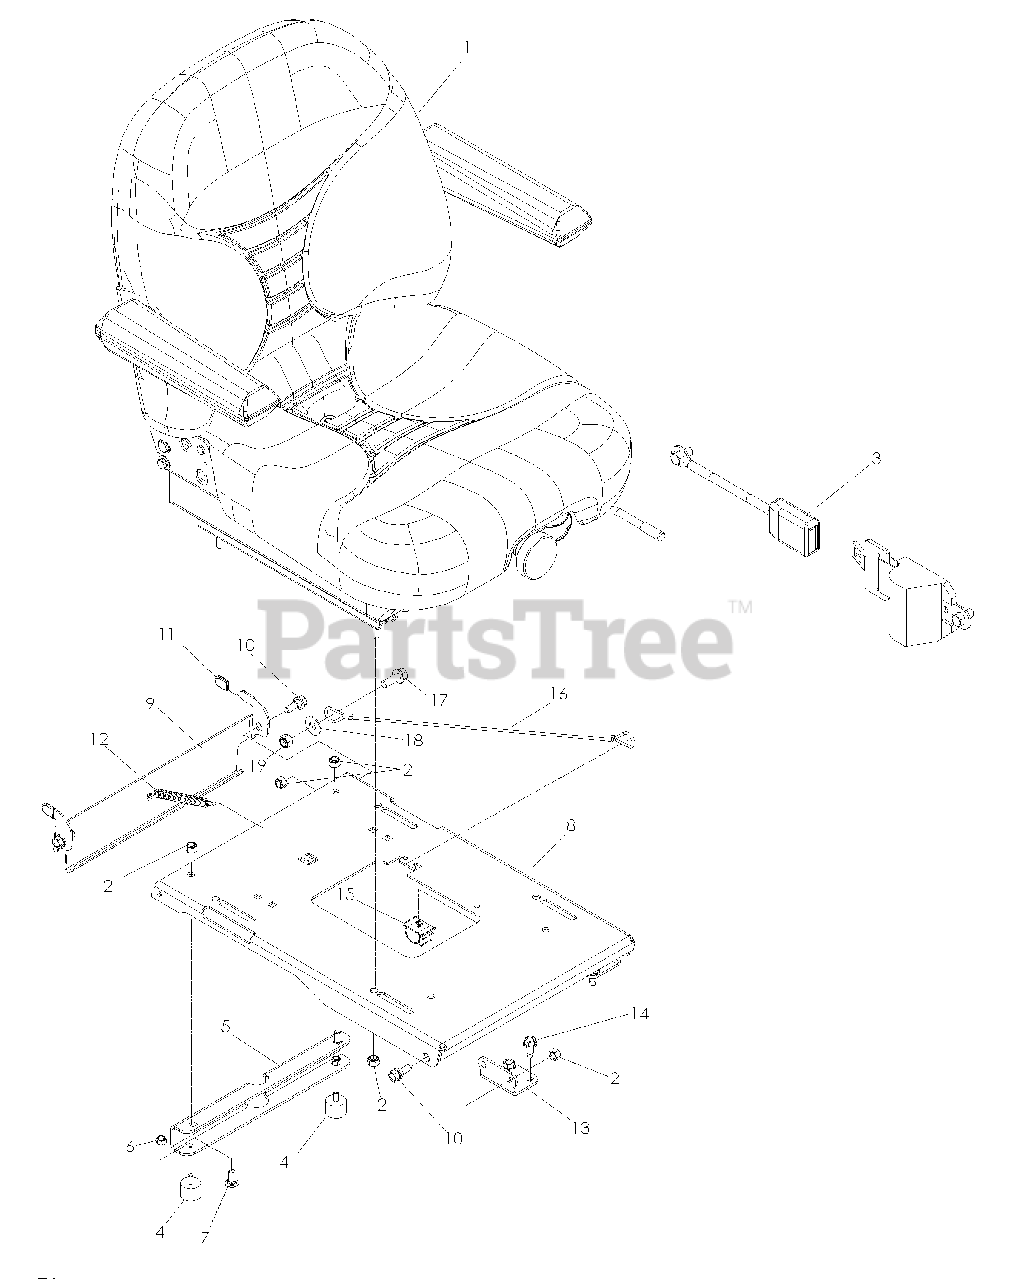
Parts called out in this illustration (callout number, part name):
2	NUT 5/16-18 HEX NYLOC
3	SEAT BELT-RETRACTABLE
4	STUD PLATE MOUNT
5	STANDOFF, SEAT PAN
6	NUT 1/4-20 HEX NYLOC
7	RHSNB 5/16-18 x 3/4
9	LATCH, SEAT
10	SB 5/16-18 HEX HD
11	GRIP, VINYL
13	PIVOT SEAT PAN
14	BOLT 5/16-18 x 3/4 THD FRM
15	WIRE CLIP PUSH-MOUNT
16	SEAT LANYARD
17	HCS 3/8-16 x 1 WHIZLK
18	WASHER 3/8 FLAT STD
19	NUT 3/8-16 HEX NYLOC
